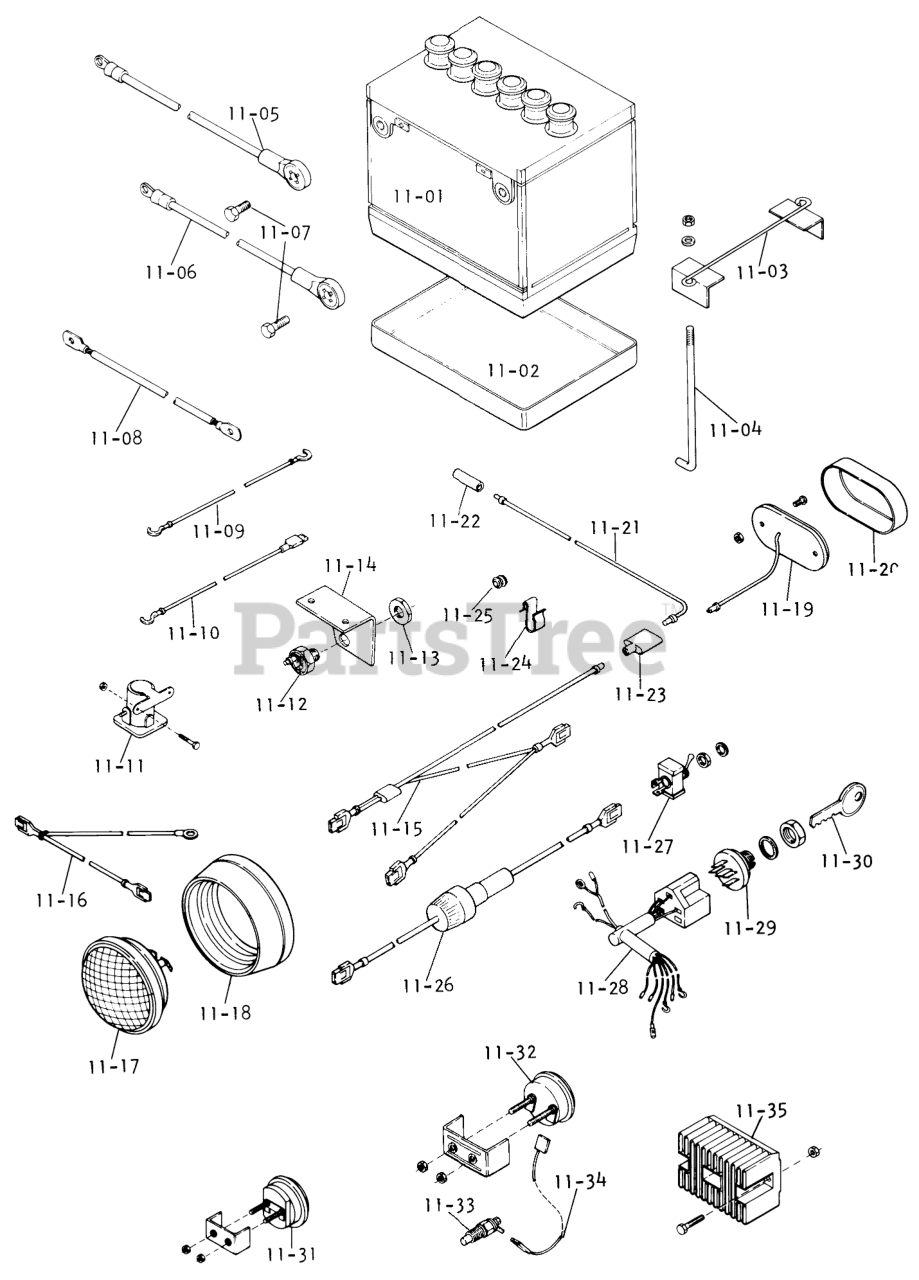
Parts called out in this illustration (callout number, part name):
11-01	Battery
11-02	Battery Box
11-03	Assy-Hold Down
11-04	Hook-Battery Retainer
11-05	Cable-Battery Positive to Solenoid (Red)
11-06	Cable-Battery Negative to Ground (Black)
11-07	Bolt, Battery Terminal-Special
11-08	Cable
11-09	WIRE ASSY
11-10	Assy-Wire
11-11	Solenoid
11-12	SWITCH SAFETY
11-13	NUT-SPECIAL 9/16-18
11-14	Bracket
11-15	Control Clip
11-16	Wire Assy
11-17	HEADLAMP
11-18	Grommet
11-19	Base-Taillight
11-20	Lens-Taillight
11-21	Wire assembly
11-22	CONNECTOR 2 WIRE
11-23	CONNECTOR 3 WIRE
11-24	SPEED CLIP
11-25	Grommet
11-26	ASSY FUSED CONNECTOR
11-27	SWITCH-LIGHTS
11-28	Harness-Main Wiring
11-29	Switch-Ignition
11-30	Key-EL
11-31	AMMETER W/CLAMP
11-31	Clamp
11-32	Gauge-Oil Temp
11-33	Assy-Thermistor
11-34	Assy-Wre
11-35	REGULATOR-RECTIFIER
